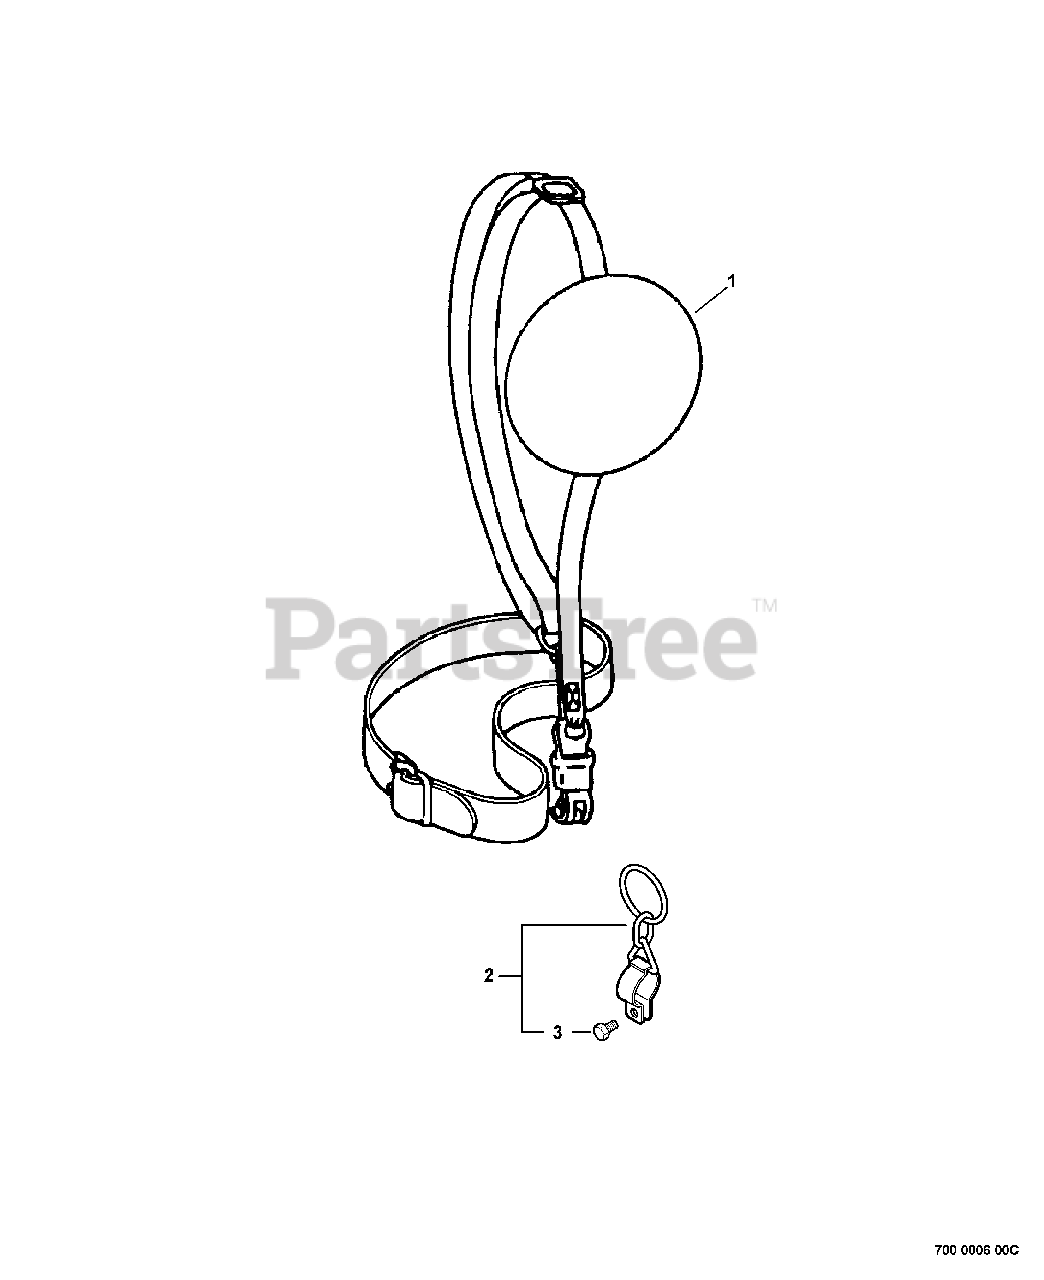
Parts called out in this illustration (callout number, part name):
1	HARNESS, SHOULDER
2	HANGER SET, HARNESS
3	BOLT 5×12
